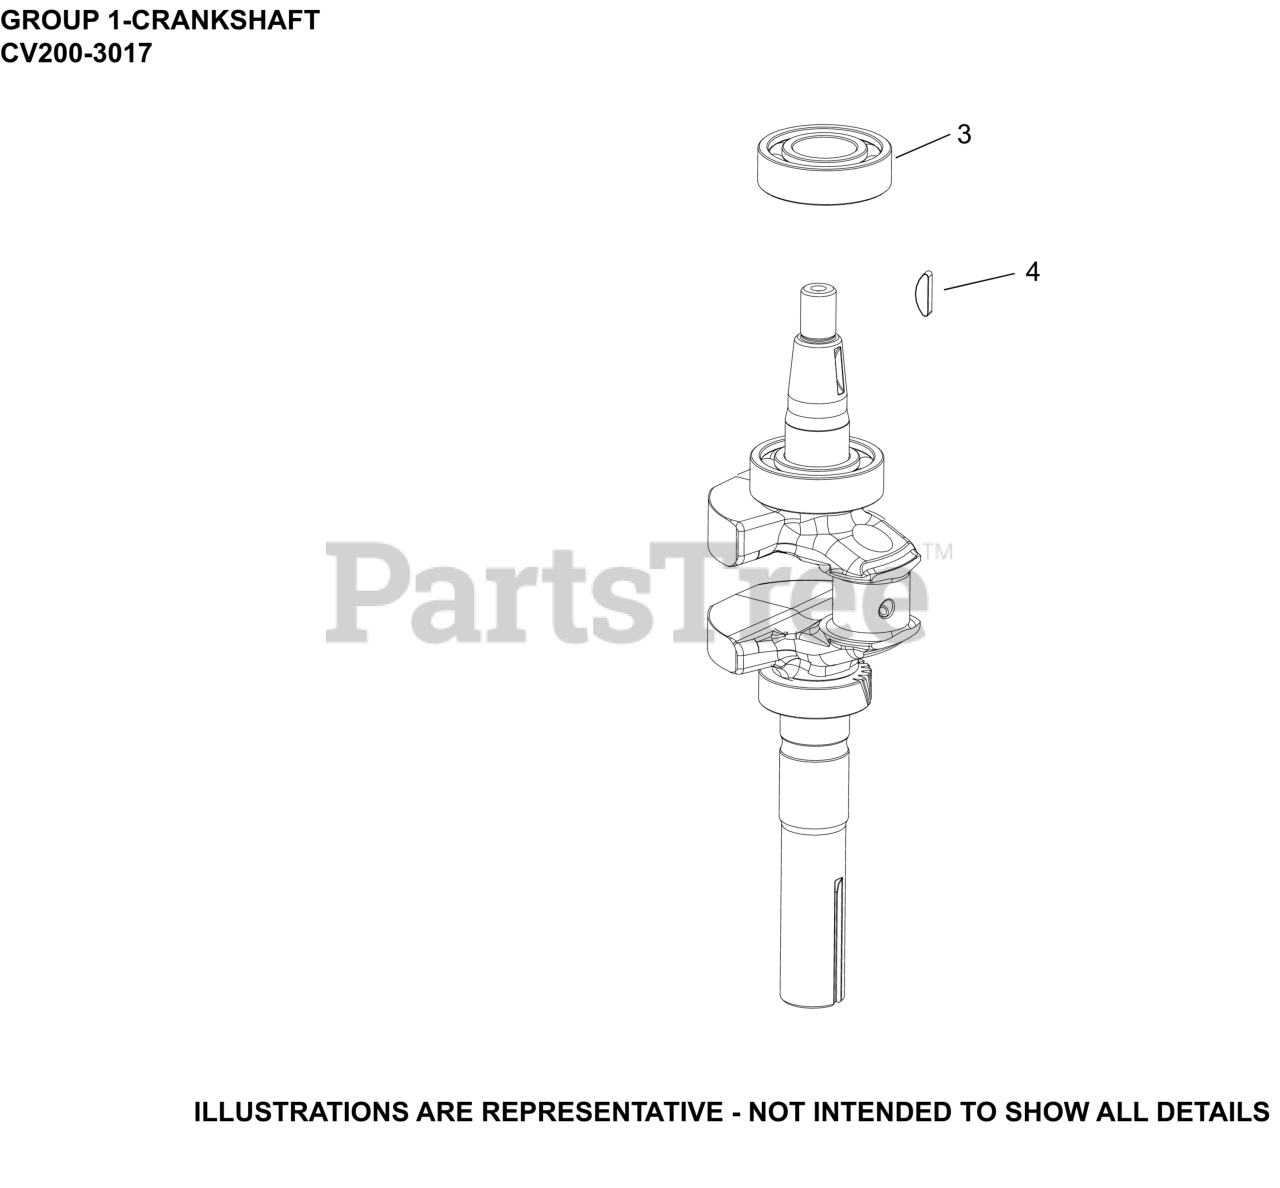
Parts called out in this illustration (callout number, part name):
3	BEARING, BALL
4	KEY, FLYWHEEL
NI	CRANKSHAFT, ASSEMBLY
